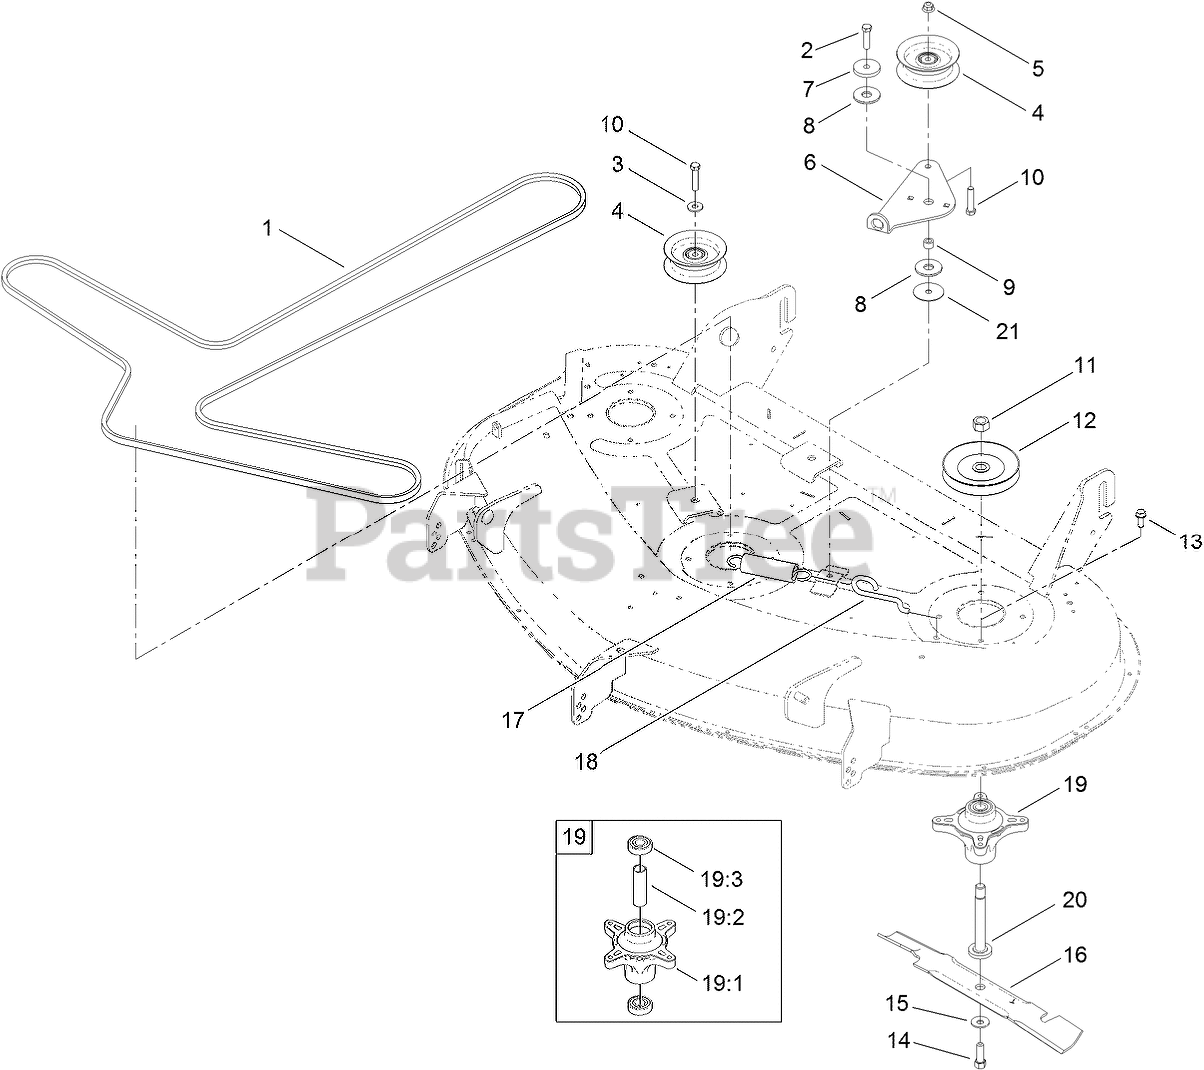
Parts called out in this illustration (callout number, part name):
1	V-BELT
2	SCREW-HH
3	WASHER-HARDENED
4	PULLEY-IDLER, FLAT
5	NUT-HF, NI
6	ARM-IDLER
7	WASHER-PLAIN
8	WASHER-FRICTION, COMPOSITE
9	SPACER
10	SCREW-HH
11	NUT-HEX
12	PULLEY
13	SCREW-TAPTITE
14	SCREW-HH
15	WASHER-BELLEVILLE
16	BLADE-HI-FLO, 17.50 INCH
17	SPRING-EXTENSION
18	HOOK-RETURN, SPRING
19	SPINDLE ASM
19:1	SPINDLE
19:2	SPACER
19:3	BEARING-BALL
20	SHAFT-SPINDLE
21	WASHER
